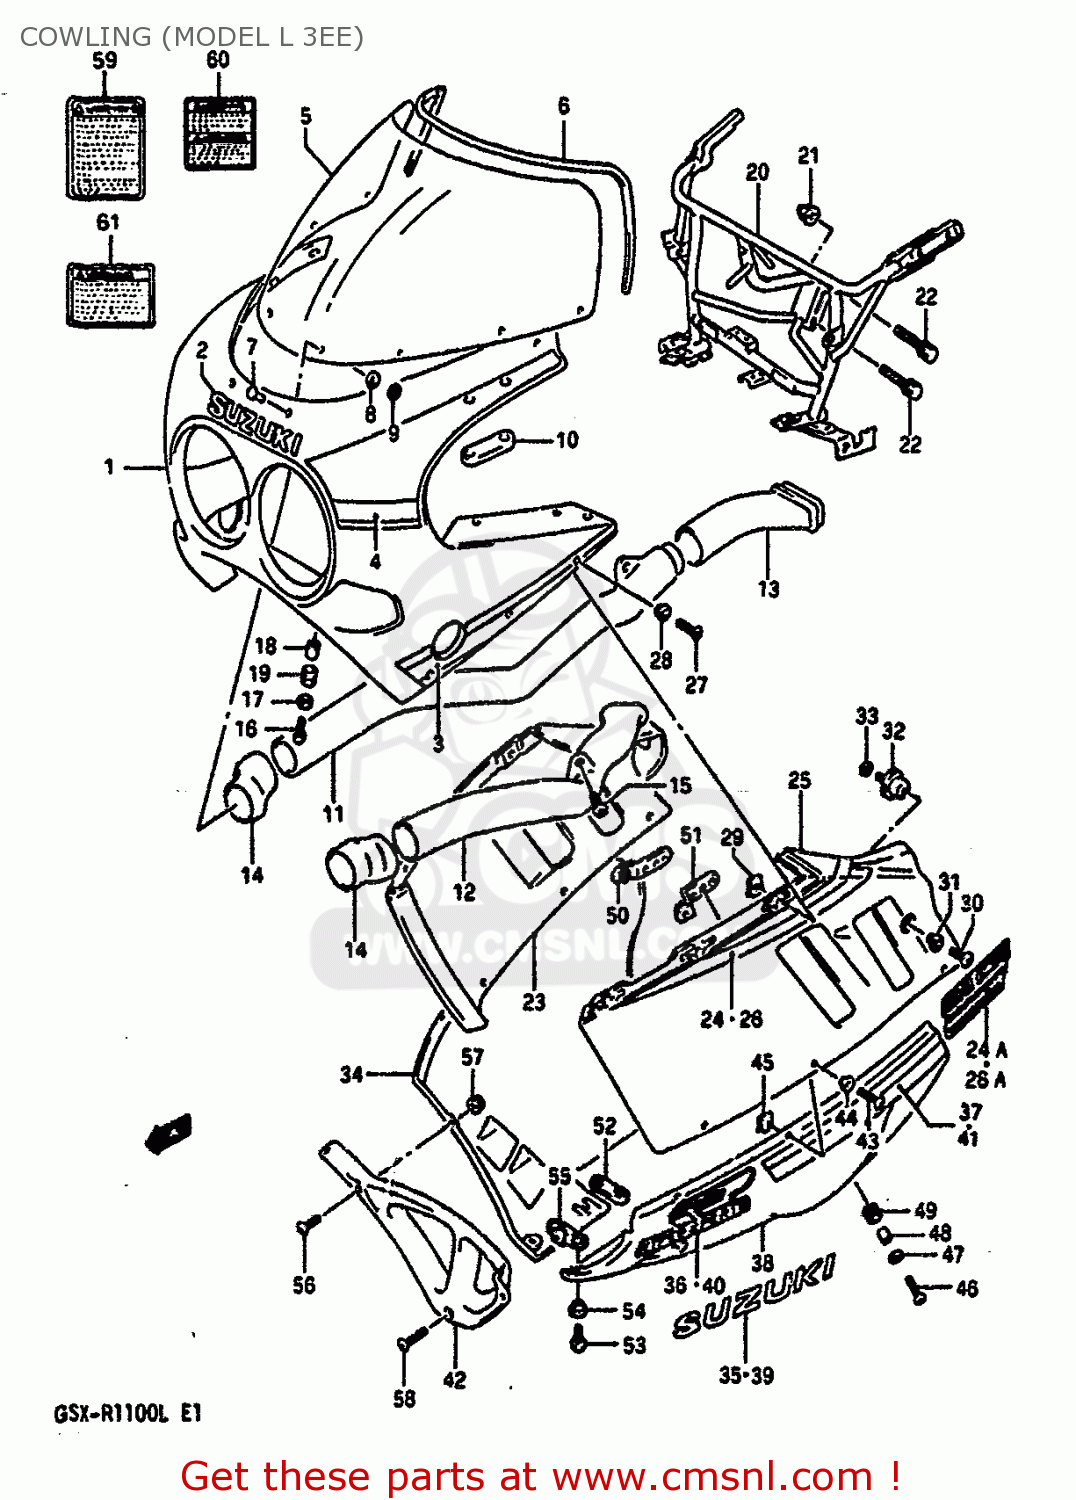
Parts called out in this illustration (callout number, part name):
1	BODY ASSY,COWLING (RED)
2	EMBLEM
3	TAPE SET,SIDE
4	TAPE SET,FRONT
5	SCREEN,WIND
6	MOLDING
7	PIN,WINDSCREEN
8	CUSHION
9	NUT
10	CUSHION,RR VIEW MIRRORR
11	PIPE,AIR INTAKE FR,R
12	PIPE,AIR INTAKE,FRONT
13	PIPE,AIR INTAKE RR,R
14	JOINT,AIR INTAKE
15	SCREW, CENTER
16	SCREW(6X20)
17	WASHER(6.5X18X1)
18	SPACER
19	CUSHION
20	BRACE,COWLING
21	NUT ,8MM
22	BOLT
23	COVER,COWLING
24	TAPE,SIDE RH
24A	EMBLEM
25	COVER,COWLING,
26	TAPE,COWL SIDE,L
26A	EMBLEM
27	SCREW(5X18)
28	WASHER(5.2X14X1.5)
29	NUT,HEADLAMP HOUSING,UPPER
30	SCREW(6X12)
31	WASHER(6.3X16X1.5)
32	CUSHION,COWLING
33	WASHER,LOCK
34	COWLING,UNDER RH (RED/BLACK)
35	EMBLEM,SUZUKI
36	EMBLEM
37	TAPE,COWL UNDER STRIPE,R
38	COWL,UNDER,L
39	EMBLEM,SUZUKI
40	EMBLEM
41	TAPE,LH
42	COWLING,UNDER FRONT (RED)
43	SCREW(5X18)
44	WASHER(5.2X14X1.5)
45	NUT,HEADLAMP HOUSING,UPPER
46	SCREW(6X20)
47	WASHER(6.5X18X1)
48	SPACER
49	CUSHION
50	BRACKET
51	BRACE,COWLING UNDER,LH
52	BRACE,COWLING LWR COVER RR
53	SCREW(6X16)
54	WASHER(6.3X16X1.5)
55	BRACE,COWLING LWR COVER
56	SCREW(5X14)
57	NUT
58	SCREW(6X16)
59	LABEL (WARNING SCREEN)
60	LABEL (WARNING)
61	LABEL, WARNING SAFETY
